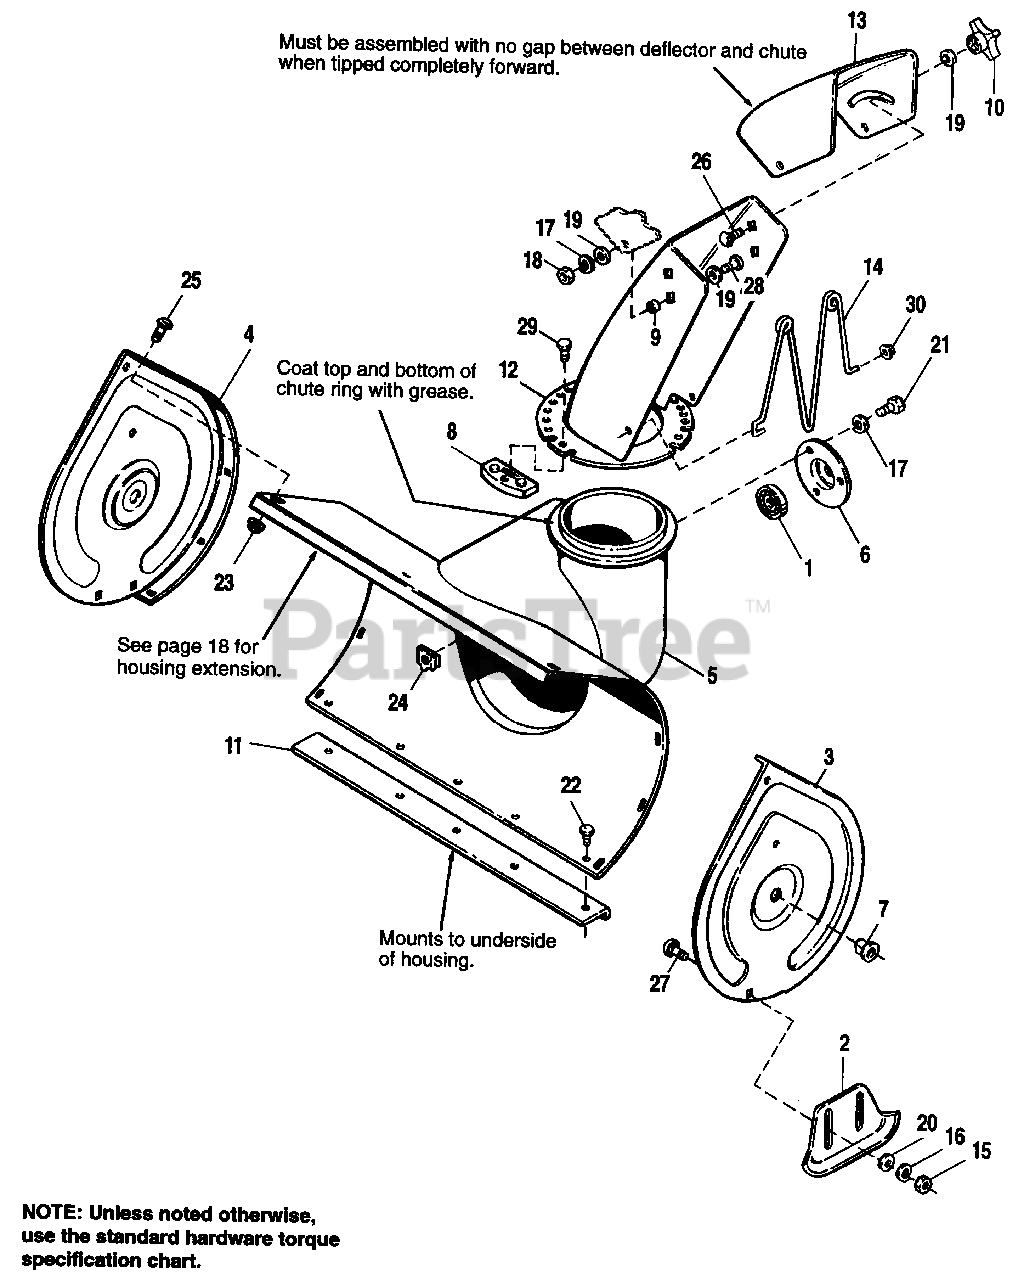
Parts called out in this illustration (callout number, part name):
1	BEARING, Ball
2	SKID
3	AUGER HOUSING END, LH
4	AUGER HOUSING END, RH
5	AUGER HOUSING ASSY.
6	RETAINER, Bearing
8	HOLD DOWN, Chute
11	SCRAPER BLADE
12	CHUTE ASSY.
14	GUARD, Chute
15	NUT, Hex, 3/8-16
16	LOCKWASHER, 3/8
17	LOCKWASHER 5/16
18	NUT, Hex, 5/16-18
19	WASHER, 5/16
20	WASHER, 5/16
21	SCREW, Hex, 5/16-18 x 5/8
22	SCREW, Taptite, 1/4-20 x 3/8
23	NUT, Hex, Flange Lock, 1/4-20
24	NUT, Retainer, 5/16-18
25	CARRIAGE BOLT, 1/4-20 x 1/2
26	CARRIAGE BOLT, 5/16-18 x 7/8, Gr. 5
27	CARRIAGE BOLT, 3/8-16 x 3/4
28	SCREW, Phillips Hd., 5/16-18 x 3/4
29	SCREW, Plastite, #10
